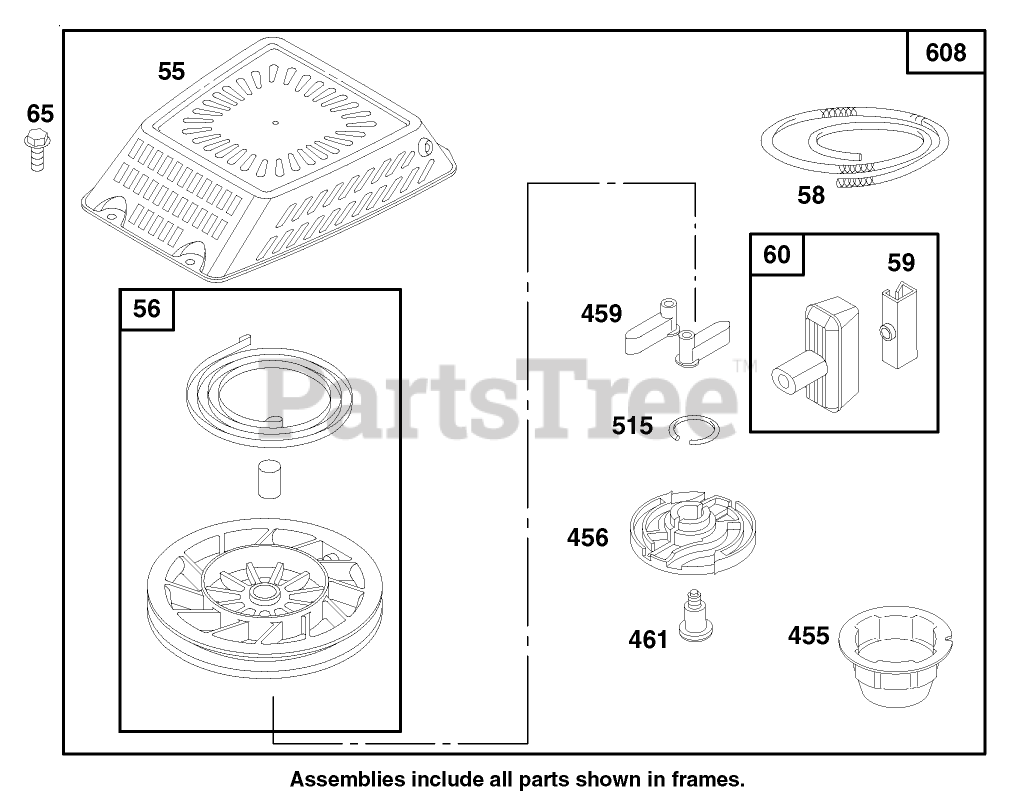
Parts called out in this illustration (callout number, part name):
56	PULLEY-STARTER, REWIND
58	ROPE-STARTER
59	INSERT-HANDLE, REWIND
455	CUP - STARTER
456	RETAINER-STARTER, REWIND
459	PAWL-STARTER
515	SPRING-TORSION
608	BRIGGS #498146
